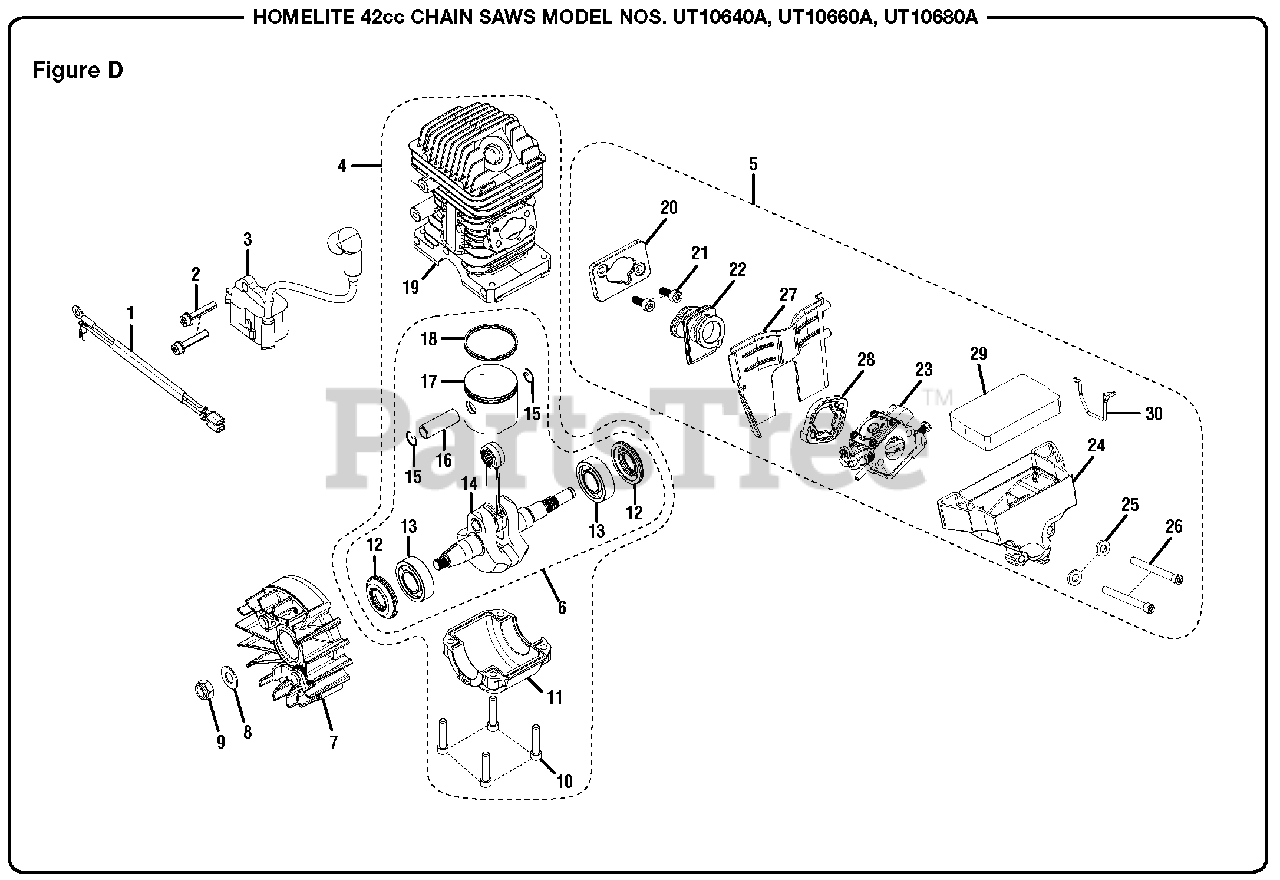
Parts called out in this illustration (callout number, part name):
1	Ignition Switch Harness
2	Bolt (M5 x 25.4 mm)
3	Ignition Module
4	Short Block Assembly
5	Intake Assembly
6	Crankshaft & Piston Assembly
7	Flywheel Assembly
8	Washer
9	Flywheel Nut
10	Screw (M5 x 24 mm)
11	Crankshaft Case
12	Crankshaft Seal
13	Ball Bearing
14	Crankshaft & Rod Assembly
15	Spring Retainer
16	Piston Pin
18	Piston Ring
20	Press Plate, Cylinder
21	Bolt (M5 x 14 mm)
22	Intake Boot
23	Carburetor
24	Air Filter Box
26	Bolt (M5 x 50 mm)
28	Press Plate, Carb
29	Air Filter
30	Throttle Rod
